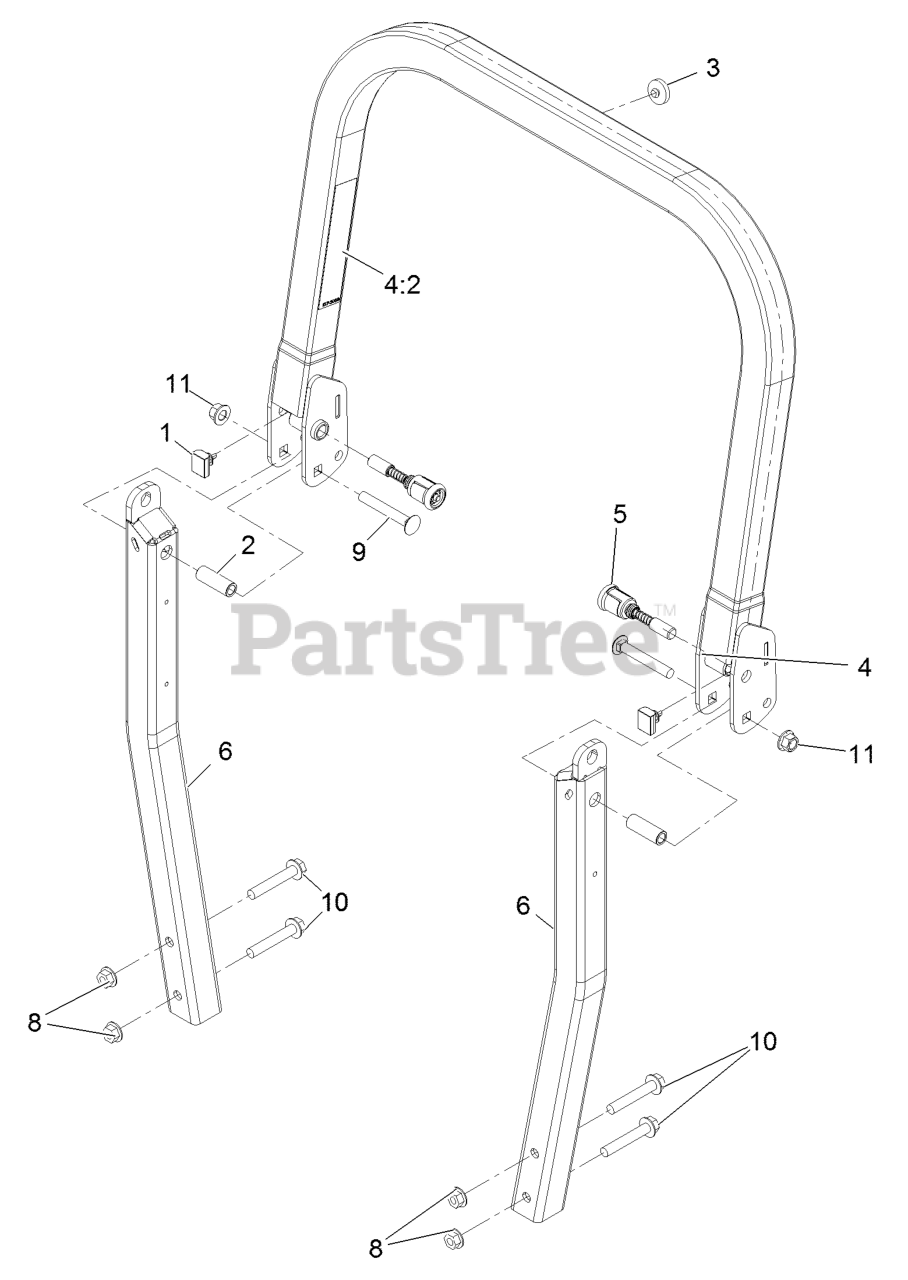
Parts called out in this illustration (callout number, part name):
1	BUMPER-ROPS
3	BUMPER-PUSH-IN, RUBBER
4	UPPER ROPS ASM
4:2	DECAL-WARNING
5	PIN-SPRING
6	NUT-HHF
8	SCREW-CARR
9	SCREW-HF
10	Nut-Lock 1/2-13
